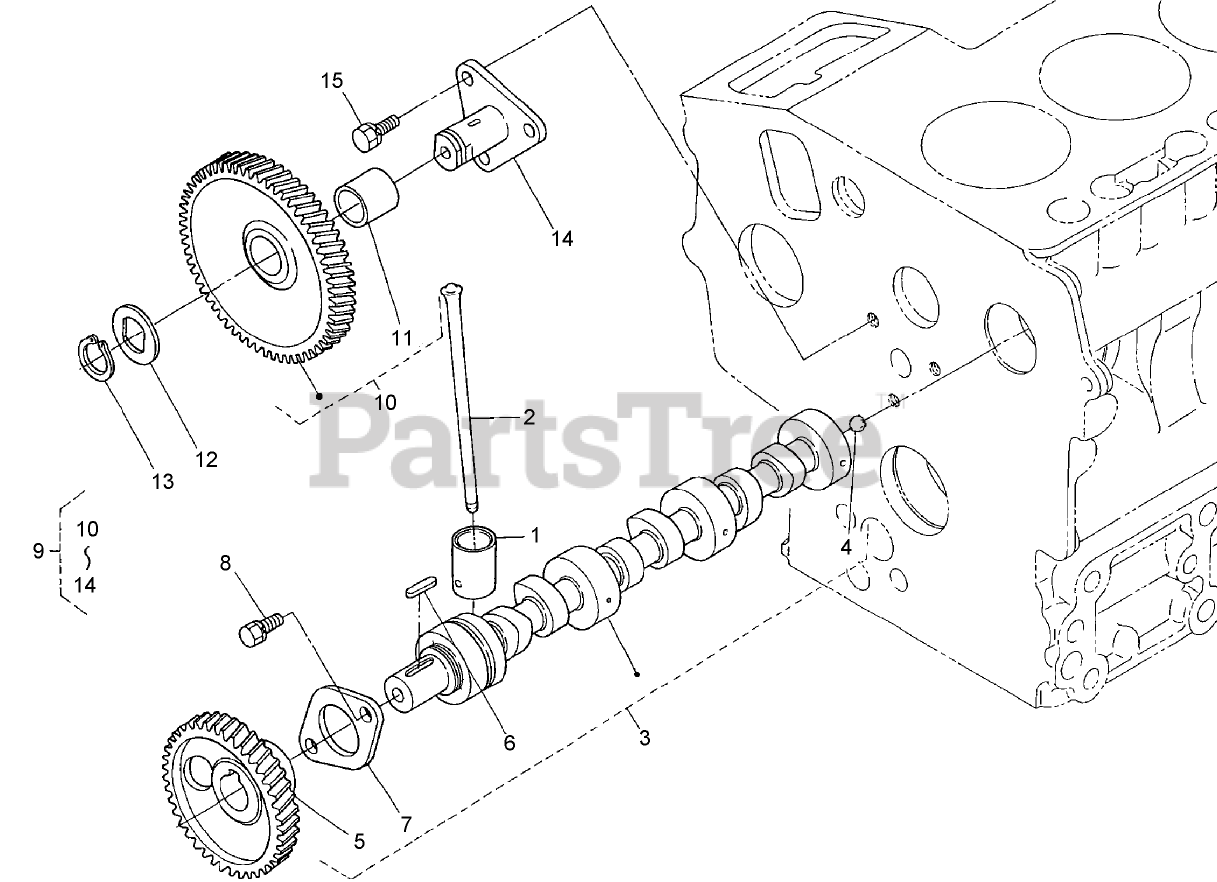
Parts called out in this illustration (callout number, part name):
1	TAPPET
2	ROD-PUSH
3	CAMSHAFT ASM
4	BALL
5	GEAR-CAM
6	KEY-FEATHER
7	STOPPER-CAMSHAFT
9	IDLE GEAR ASM
10	GEAR-IDLE
11	BUSHING
12	COLLAR-GEAR, IDLE
13	RING-SNAP
14	SHAFT-GEAR, IDLE
